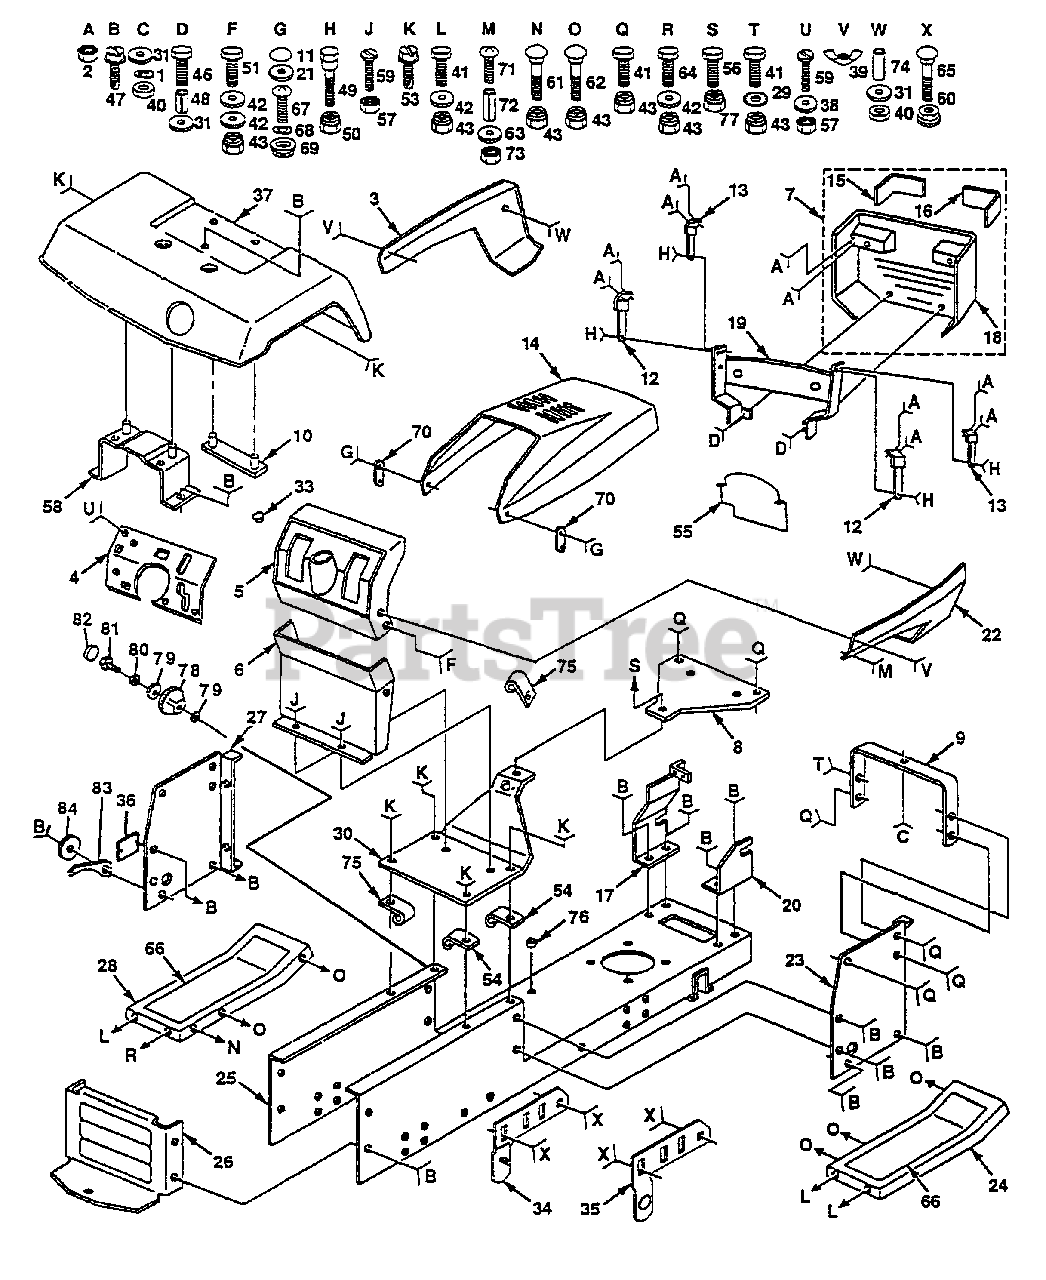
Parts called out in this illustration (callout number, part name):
1	Washer, Lock, Hvy Hlcl 1/4
2	Nut, Hex, Keps 1/4-20 UNC
3	Side Panel, LH
4	Plate, Dash
5	Dashboard
6	Dash, Lower
7	Grill Assembly
8	Plate, Battery Support
9	Support, Dash
10	Strap, Fender
11	Cap, Black
12	Strap Assembly, Hinge, Rear
13	Strap Assembly, Hinge, Front
14	Hood
15	Lens, Headlight, LH, Smoked
16	Lens, Headlight, RH, Smoked
17	Pivot Bracket Assembly, LH
18	Grille
19	Support Assembly, Grille
20	Pivot Bracket Assembly, RH
21	Washer, Cap
22	Side Panel, RH
23	Dash Panel, RH
24	Footrest, RH
26	Drawbar
27	Dash Panel, LH
28	Footrest, LH
29	Washer, Lock, External Tooth 3/8
31	Washer 9/32 x 3/4 x 16 Gauge
33	Plug, Button
34	Pivot Bracket Assembly, Rear, LH
35	Pivot Bracket Assembly, Rear, RH
36	Cover Access
38	Washer 11/32 x 11/16 x 16 Gauge
39	Wing Nut, Plastic 1/4-20
40	Nut, Hex, Fin. 1/4-20 UNC
41	Bolt, Hex, Fin. 3/8-16 UNC x 3/4
42	Washer 13/32 x 13/16 x 12 Gauge
43	Nut, Crownlock 3/8-16 UNC
46	Bolt, Hex 1/4-20 x 2-1/2
47	Screw, Thd., Roll. 3/8-16 x 3/4
48	Spacer, Split
49	Bolt, Shoulder 1/4-20 UNC
50	Nut, Crownlock 1/4-20 UNC
51	Bolt, Hex, Fin. 3/8-16 UNC x 1-1/4
53	Screw, Thd., Roll. 3/8-16 x 1/2
54	Clip, Insulator
55	Baffle, Vertical
56	Bolt, Hex, Fin. 5/16-18 UNC x 3/4
57	Nut, Hex, Keps 5/16-18 UNC
58	Bracket Fender
59	Screw, Machine 5/16-18 UNC x 3/4
60	Locknut, Hex, with Washer Insert 3/8-16 UNC
61	Bolt, Carriage 3/8-16 UNC x 1
62	Bolt, Carriage 3/8-16 x 3/4
63	Washer 7/32 x 1/2 x 18 Gauge
64	Bolt, Hex, Fin. 3/8-16 UNC x 7/8
65	Bolt, Carriage 3/8-16 UNC x 1
66	Pad, Footrest
67	Screw, Machine, Cross Pan Head #10-24 x 1/2
68	Washer, Lock #10
69	Nut, Weld
70	Latch, Chute
71	Screw, Machine, Cross Pan Head #10-24 x 1-1/4
72	Spacer, Split #10 x 3/4
73	Nut, Hex, Keps #10-24 UNC
74	Spacer 17/64 x 1/2 x 3/8
75	Clip, Fuel Line
76	Bushing, Snap Split
77	Nut, Crownlock 5/16-18
78	Scale Ind. Height
79	Washer 11/32 x 1-1/2 x 10 Ga.
80	Washer Lock Hvy Hlcl Spr. 5/16
81	Bolt Hex 5/16-18 x 1
83	Pointer Pnt Height Ind.
84	Washer Nylon
